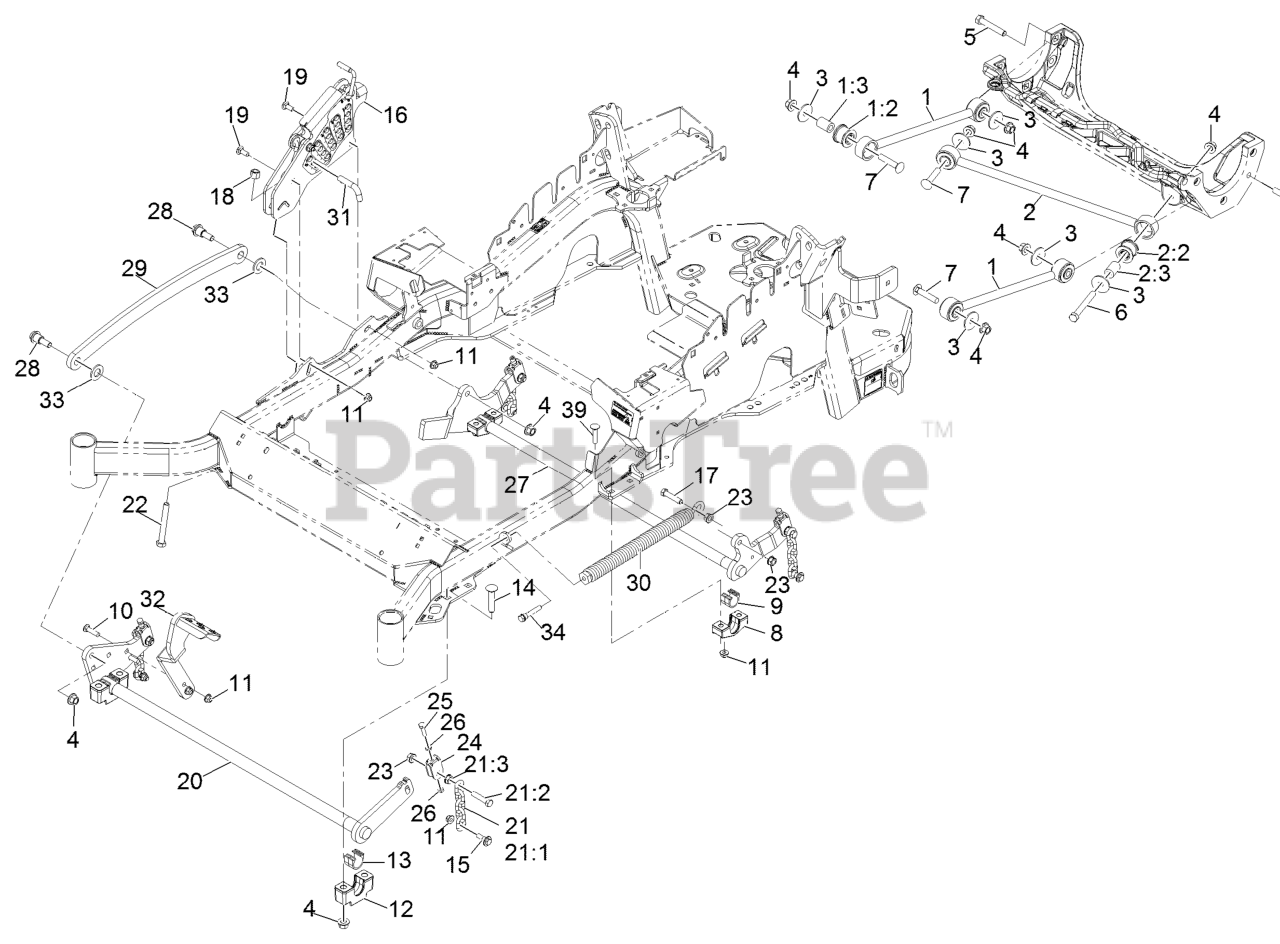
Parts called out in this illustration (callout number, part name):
1	DECK STRUT ASM
1:2	BUSHING-SUSPENSION, RUBBER
2	PANHARD ROD ASM
2:2	BUSHING-SUSPENSION, RUBBER
3	WASHER-THRUST
4	Nut-Lock 1/2-13
5	SCREW-HH
6	SCREW-HH
7	SCREW-CARR
9	BEARING-CROSS SHAFT, REAR
10	SCREW-CARR
11	NUT-HF, NI
12	SUPPORT-CROSS SHAFT, BEARING
13	BEARING-CROSS SHAFT, FRON
14	Bolt-Carriage 1/2-13 X 2 1/2 Spl Neck
15	SCREW-SHOULDER, HHF
16	HOC ASM
17	SCREW-HH
18	NUT-LOCK, NI
19	BOLT-CARR
21	DECK LIFT CHAIN ASM
21:1	CHAIN-LIFT, DECK
21:2	SCREW-HH
22	BOLT-TAP
24	YOKE-ADJUST, DECK
25	SCREW-HH
26	NUT-JAM
27	LIFT-DECK, REAR
28	SCREW-SHOULDER, HHF 1/2-13 X 1.12
29	LINK-LIFT, DECK
30	SPRING-EXTENSION
31	PIN-HOC
32	LEVER-FOOT
33	WASHER-FLAT
34	BOLT-SHOULDER
39	SCREW-CARR
